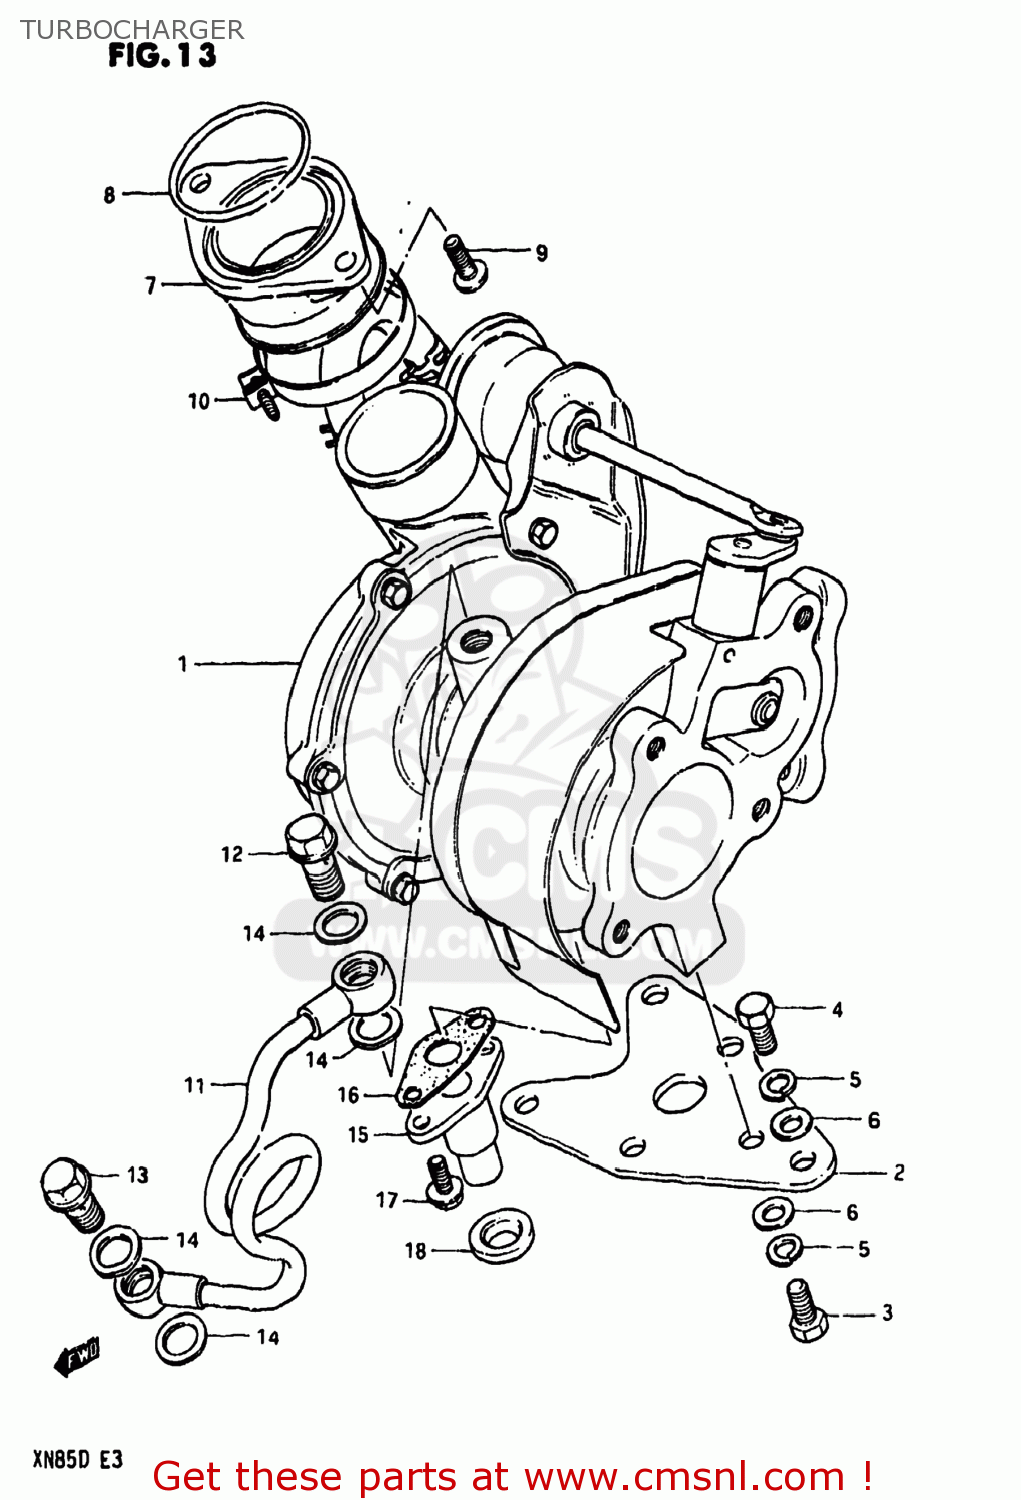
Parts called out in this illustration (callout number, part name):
1	CHARGER ASSEMBLY,TURBO
2	CHARGER ASSEMBLY,TURBO
3	BOLT
4	BOLT
5	LOCK WASHER
6	WASHER
7	COVER
8	O-RING
9	SCREW
10	CLAMP
11	TANK COMP,OIL CATCH
12	BOLT UNION
13	BOLT UNION
14	GASKET(10X15X1)
15	CONNECTOR, OIL OUTLET
16	GASKET (MCA)
17	BOLT
18	OIL SEAL
